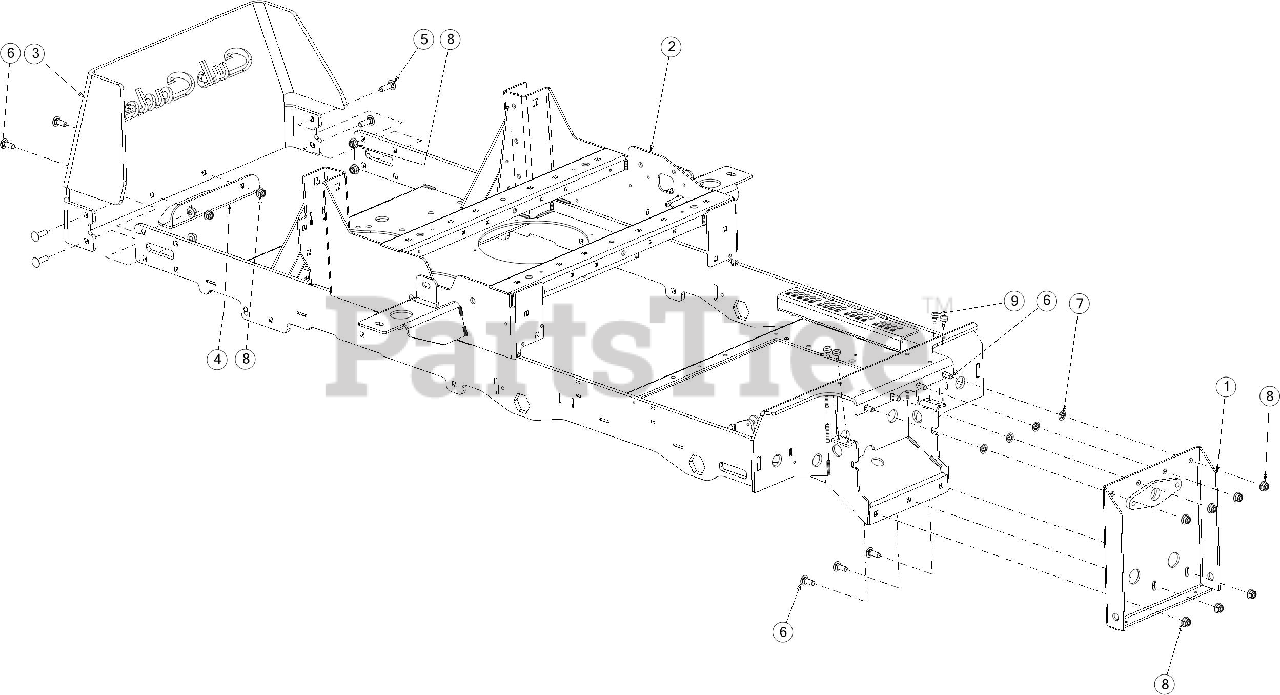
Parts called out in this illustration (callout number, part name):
2	FRAME ASSEMBLY
3	REAR TAILGATE BUMPER
5	CARRIAGE BOLT 3/8-16 X1.25 GR5
6	CARRIAGE BOLT 3/8-16 X 1.00 GR5
9	BUMPER, .62 DIA X .3
